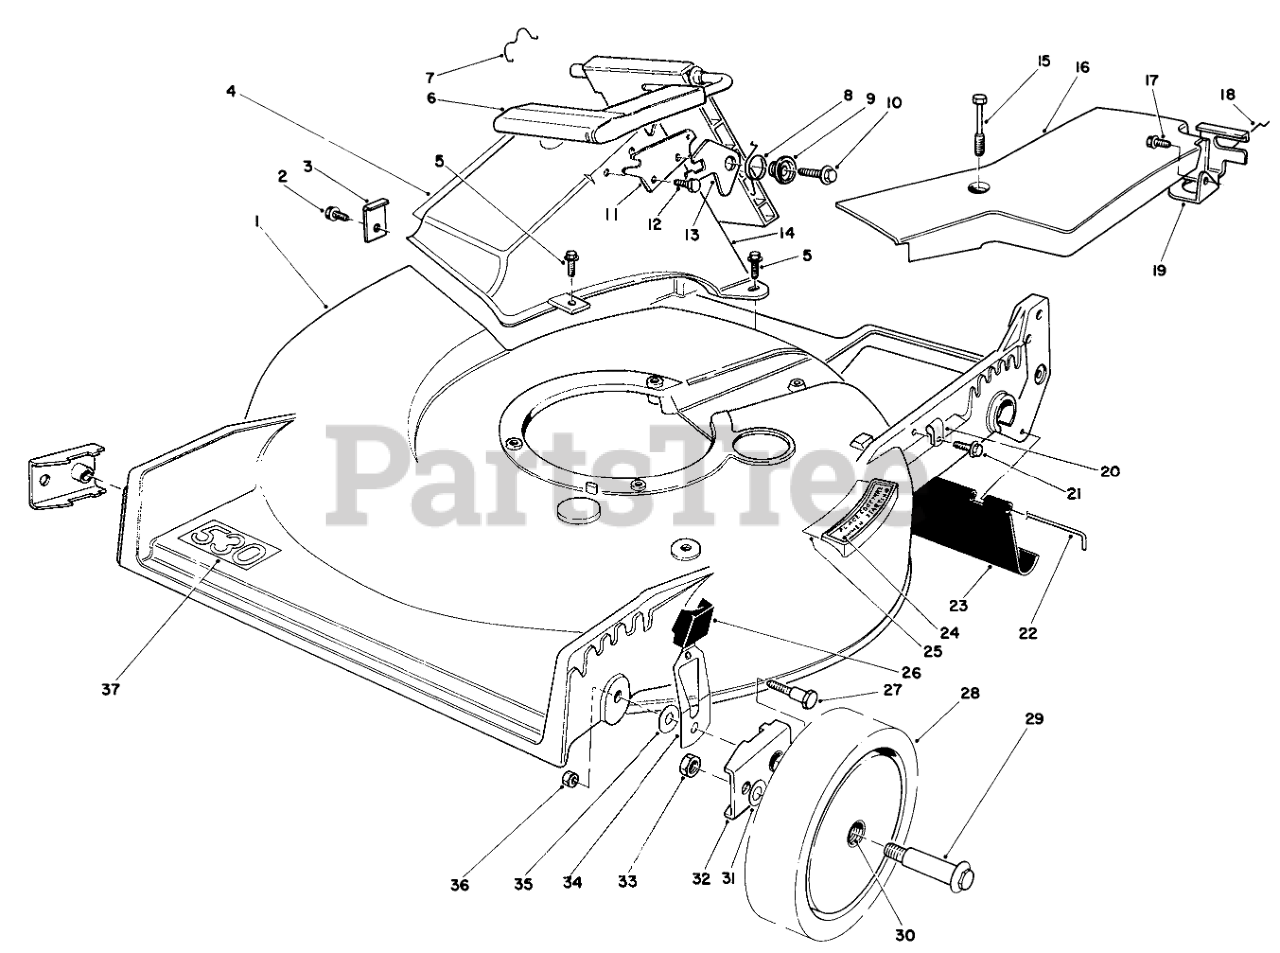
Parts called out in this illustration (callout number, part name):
1	21 SP RB HSG/DECAL
2	SCREW
3	TUNNEL CLIP
4	Decal-Attention
5	SCREW-HWH
6	Discharge Door Assembly
7	DOOR RET SPRING
8	TORSION SPRING
9	DOOR SPACER
10	SCREW-HWH
11	DOOR LATCH PLATE
12	SCREW-PLASTITE
13	SAFETY LATCH
14	Tunnel Discharge
15	SCREW-HHFTF
16	Cover-Belt
17	SCREW-HWHTF
18	RETAINER-CABLE
19	Bracket-Traction Adj.
20	CLAMP-CABLE
21	SCREW
22	ROD-SHIELD
23	SHIELD-TRAILING
24	STEP PAD DECAL
25	Decal-Place Foot Here
26	KNOB-ARM
27	PIVOT SCREW
28	Wheel & Tire Assembly (Incl. Ref. #30)
29	WHEEL BOLT
30	BUSHING
31	WASHER
32	HP PIVOT ARM ASM
33	NUT-LOCK
34	Spring Arm
35	WASHER-PIVOT
36	NUT-LOCK, NI
37	Decal-530
